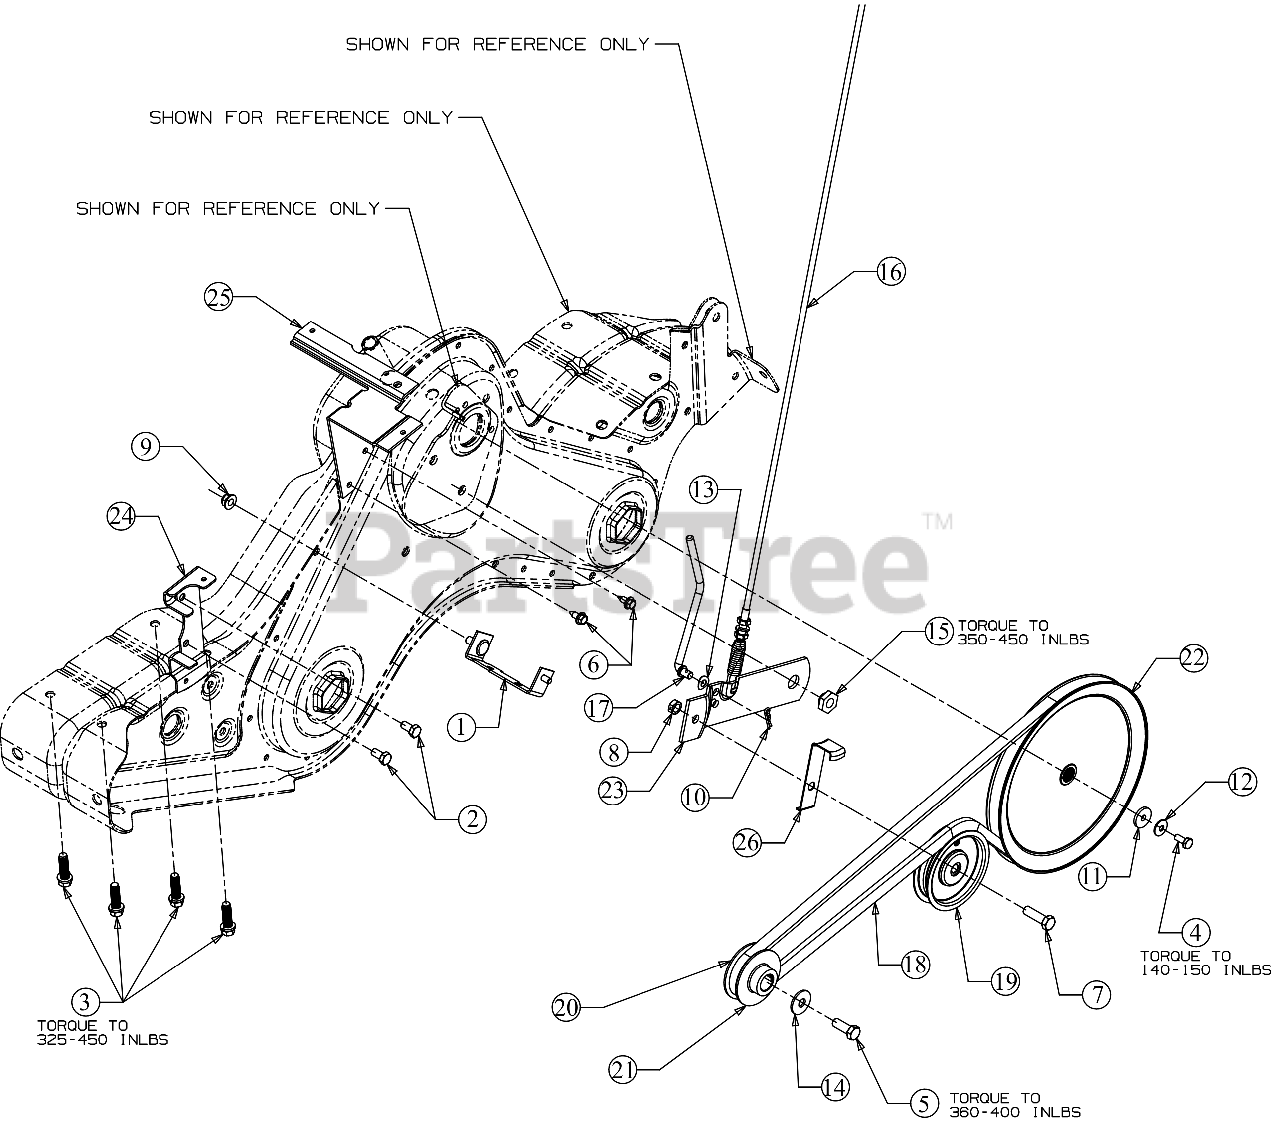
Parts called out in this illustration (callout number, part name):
1	BELT COVER BRACKET ASSEMBLY
1	WELD BOLT 5/16-18 X .875
2	HEX SCREW 5/16-24 X .62
3	SCREW 3/8-16 X 1.250
4	BOLT 1/4-28 X .625 GR8
5	SCREW 3/8-24 X 1.00 GR8
6	SCREW 1/4-20X.625
7	SCREW 3/8-16 X 1.25 GR5
8	JAM LOCK NUT
9	FLANGE LOCK NUT 5/16-18
10	COTTER PIN .072 DIA
11	FLAT WASHER
12	SPRING WASHER BELL
13	SPRING WASHER .317 X .625 X .020
14	BELL WASHER
15	SHOULDER NUT
16	CLUTCH CABLE
17	IDLER PULLEY ROD
18	BELT 1/2 X 58.16
19	IDLER PULLEY
20	ENGINE PULLEY INNER HALF
21	ENGINE PULLEY OUTER HALF
22	INPUT PULLEY
23	IDLER BRACKET
24	BELT KEEPER BRACKET
25	SHIFT COVER BRACKET
26	IDLER BELT KEEPER
